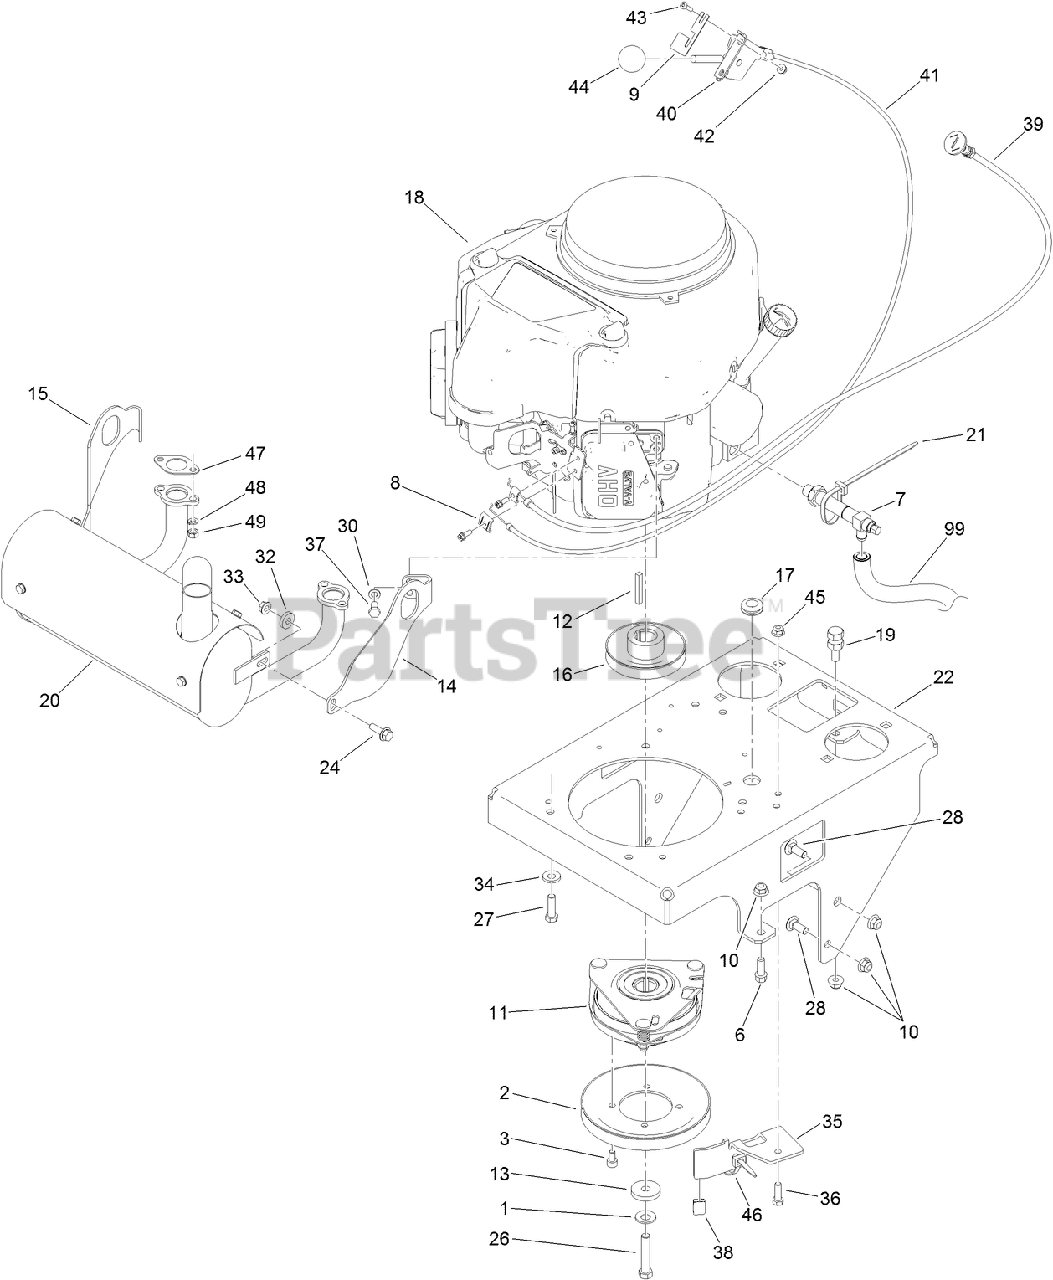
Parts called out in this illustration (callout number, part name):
1	WASHER-SPRING
2	PULLEY
3	SCREW-HSH
6	SCREW-HWH
7	VALVE-DRAIN OIL
8	CLAMP-CABLE
9	PLATE-SET, THROTTLE
10	NUT-HF, NI
11	CLUTCH/BRAKE ASM
12	KEY-SQUARE
13	WASHER
14	BRACKET-MUFFLER MOUNT, LH
15	BRACKET-MUFFLER MOUNT, RH
16	PULLEY
17	GROMMET
19	ANCHOR-SPRING, SHORT
20	MUFFLER
21	TIE-CABLE
22	BASE-ENGINE
24	SCREW-HHF
26	SCREW-HH
27	SCREW-HH
28	BOLT-CARR
30	WASHER-LOCK
32	SPACER
33	NUT-HF
34	WASHER-BELLEVILLE
35	BRACKET-CLUTCH STOP
36	SCREW-HH
37	SCREW-HH
38	BUMPER
39	Control-Choke, Push / Pull
40	LEVER-CONTROL
41	CABLE-CONTROL
42	NUT-LOCK, FLANGE
43	SCREW-TORX
44	KNOB-BALL
45	NUT-HF, NI
46	TIE-CABLE
47	GASKET-EXHAUST
48	WASHER-LOCK
99	HOSE-DRAIN, OIL
